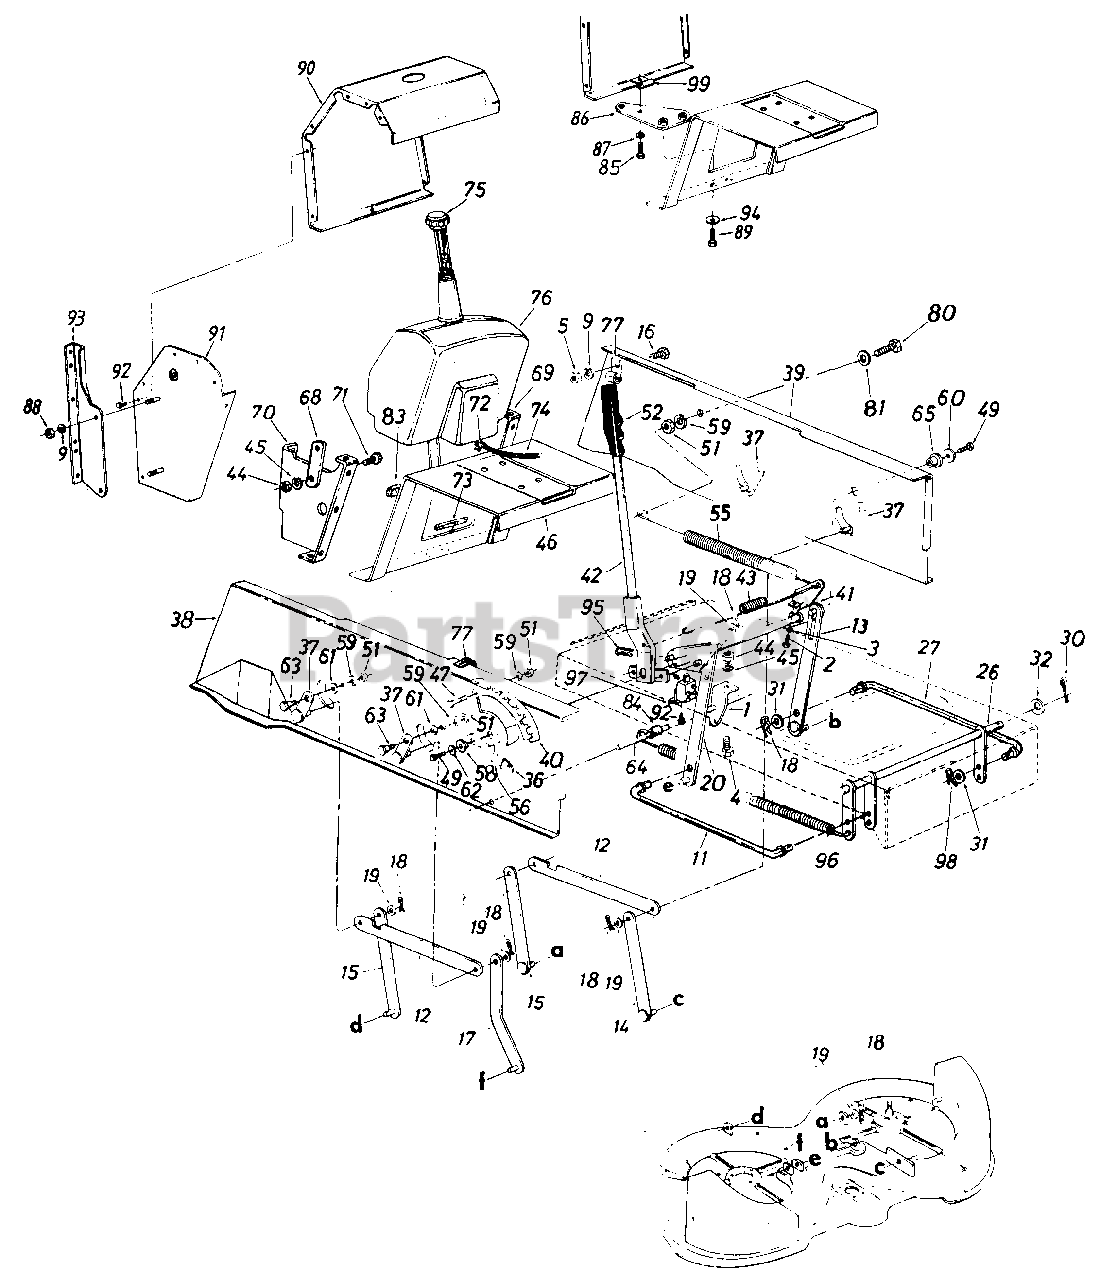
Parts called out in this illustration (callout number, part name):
1	Spring Hanger Bracket
2	Hex Tap. Scr. 5/16-18 x 1
3	Hex Jam Nut 5/16-18 Thd.
4	Hex Bolt 1/4-20 x .62" Lg.*
5	Hex Nut 5/16-18 Thd.
9	L-Wash. 5/16" I.D.*
11	Stabilizer Rod
12	Connecting Rod
13	Deck Lift Link Ass'y.
14	Deck Hanger Link Ass'y.-Rear L.H.
15	Deck Hanger Link Ass'y.
16	Hex Bolt 5/16-18 x .75" Lg.
17	Deck Hanger Link Ass'y.-
18	Inter. Cotter Pin 1/2" Dia.
19	Fl-Wash. .531 I.D. x.93" O.D.
20	Deck Lift Link Ass'y.
26	Stabilizer Shaft Ass'y.
27	Stabilizer Rod
30	Cotter Pin 1/8" Dia. x 1.25"
31	Fl-Wash. .385" I.D. x .620" O.D.
32	Fl-Wash. .635" I.D. x 1.12" O.D.
36	Knob-Height Adj.
37	Pivot Link Ass'y.
38	Side Panel Upper Frame-R. H.
39	Side Panel Upper Frame-L. H .
40	Index Brkt.
41	Lift Shaft Ass'y.
42	Lift Handle Brkt. Ass'y.
43	Ex. Spring
44	Hex Nut 1/4-20 Thd.
45	L-Wash. 1/4" I.D.
46	Hitch Plate
47	Hex Bolt 5/16-18 x .75" Lg.
49	Hex Wash. TT-Tap Scr. 5/16-18 x .62" Lg.
51	Hex Nut 5/16-18 Thd.
52	Grip
55	Ext. Spring 11" Lg.
56	Deck Lift-Down Stop
58	Flange Brg. .630" I.D.
59	L-Wash. 5/16" I.D.*
60	Fl-Wash. .344" I.D.
61	Bell-Wash. .325" I.D. x .930" x.045"
62	Fl-Wash. .344" I.D. x 1.125" O.D.
63	Shld. Bolt .437" Dia. x .180
64	Running Board Rod
65	Flange Brg. .632" I.D.
68	Fender Support Brkt.
69	Grass Catcher Support Brkt.-L.H.
70	Grass Catcher Support Brkt.-R.H.
71	Hex Bolt 1/4-20 x .50" Lg.
72	Hose Clamp-.406" Dia.
73	Trim Strip-5" Lg.
74	Gas Line-44" Lg.
75	Gas Tank Cap
76	Gas Tank
77	Hose Clamp
80	Hex Bolt 5/16-18 x 1.50" Lg.
81	Fl-Wash. .344" I.D. x .875" O.D.
83	Foam Strip 3/8" x 1-1/8" x 11/2" Lg.
84	Spacer .523" I.D. x .640" O.D. x 1.95" Lg.
85	Hex Bolt 5/16-18 x 1" Lg. Gr. 5
86	Hitch Bar
87	L-Wash. 5/16" I.D.
88	Hex Nut 5/16-18 Thd.
89	Self-Tap Scr. 3/4" Lg.
90	Gas Tank Housing
91	Side Panel-R.H.
93	Mounting Bracket-R.H.
94	Bell-Wash. 3/8" I.D.
95	Internal Cotter Pin 3/8" Dia.
96	Ext. Spring 13.25" Lg.
97	Safety Switch
98	Cotter Pin 3/32" Dia.
99	Speed Nut
